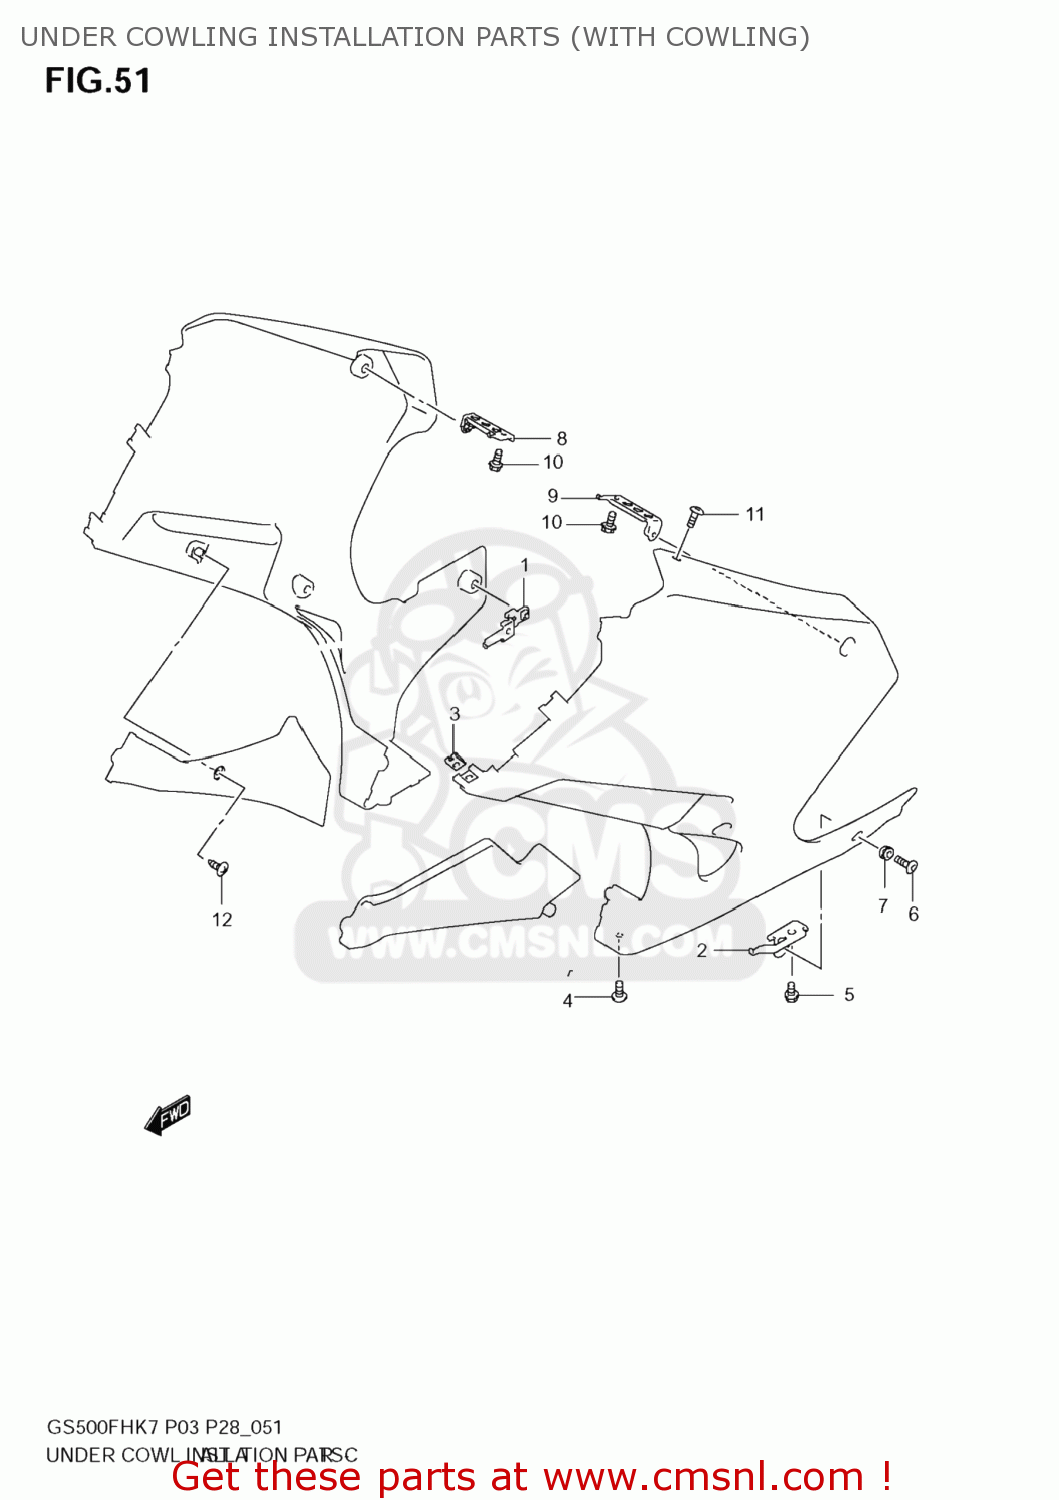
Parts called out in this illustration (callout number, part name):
1	BRACKET,LOWER
2	BRACKET, LOWER
3	NUT
4	CLIP
5	BOLT
6	SCREW(6X20)
7	CUSHION
8	BRACKET,REAR R
9	BRACKET,REAR L
10	BOLT
11	SCREW(5X16)
12	SCREW
